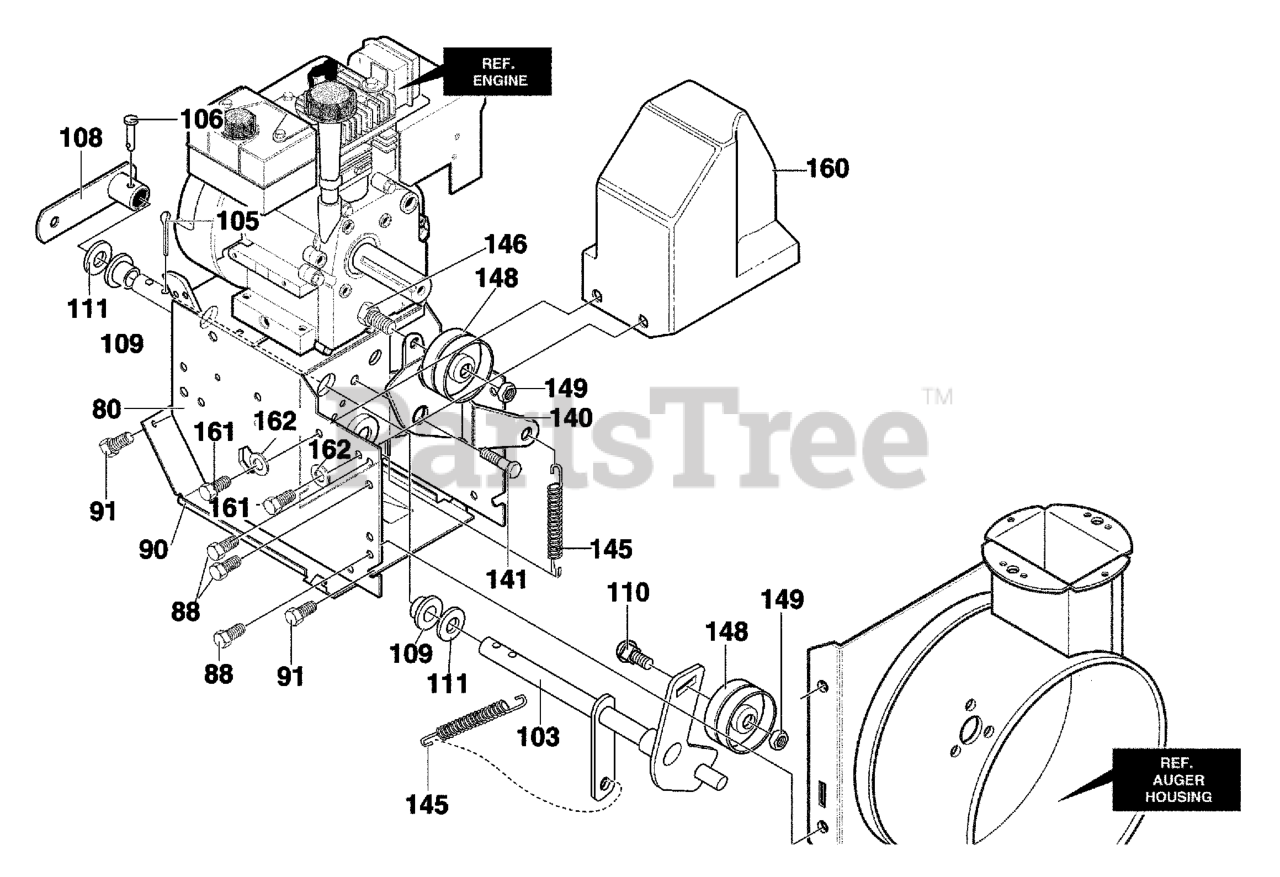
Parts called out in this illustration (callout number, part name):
80	FRAME, ASSY
88	SCREW, 5/16-18 x 0.50
90	COVER, BOTTOM
91	SCREW, 1/4-20X.63 WAHHTAP
103	ASSY., IDLER
105	HAIR PIN
106	CLIP, KLIK
108	ASSY.,SPRING ATTACH WHEEL
109	BEARING, FLANGE
110	BOLT 3/8-16X1.25
111	FLATWASHER
140	LEVER, IDLER ARM TRACTION
141	BOLT, 5/16-18
145	SPRING, IDLER TRACTION DR
146	SCREW, 3/8-16 x 1.25
148	PULLEY, IDLER
149	NUT, 3/8-16 CTRLKJAM
160	BELT COVER
161	SCREW, 1/4-20X.63 WAHHTAP
162	FLATWASHER, .281X.63X.065
